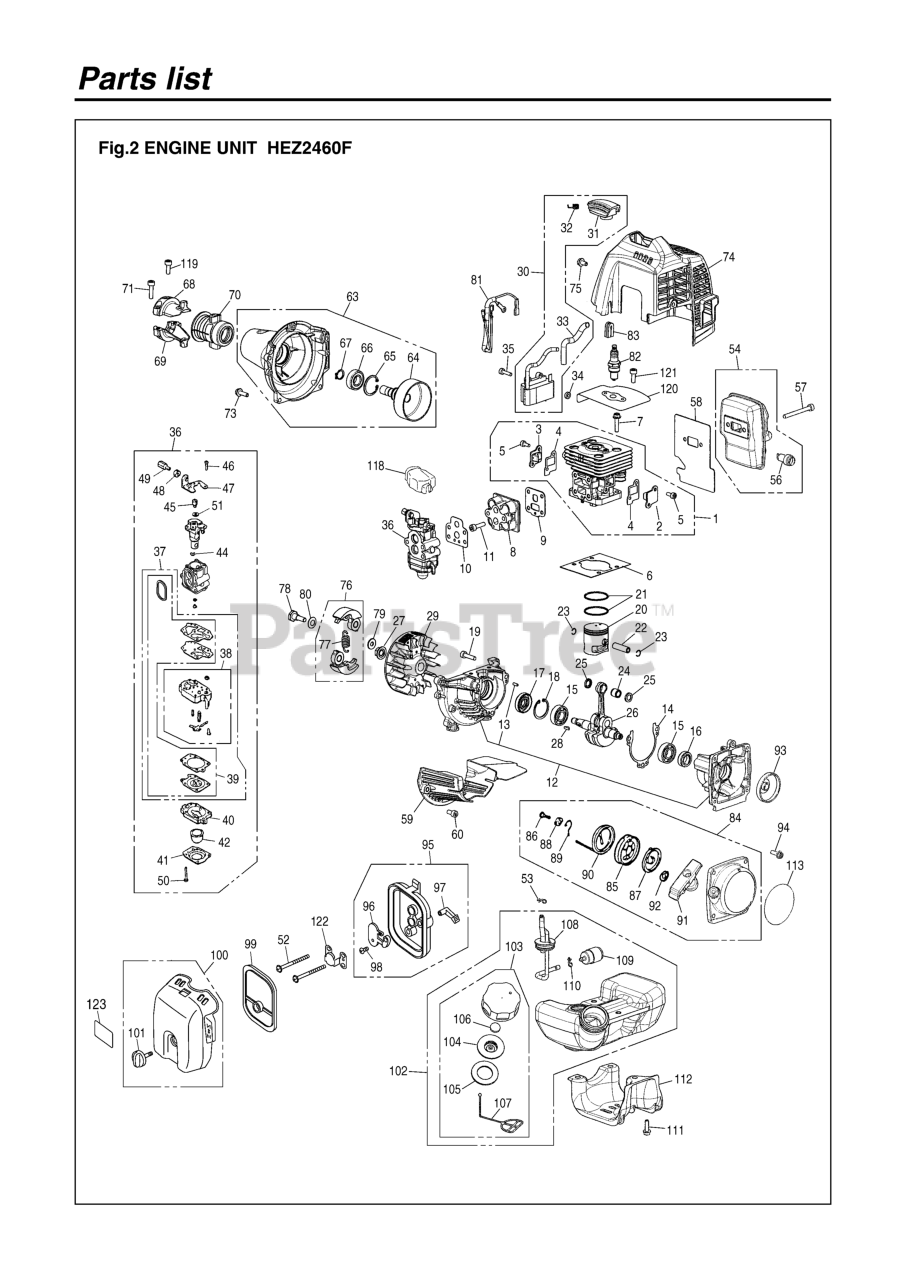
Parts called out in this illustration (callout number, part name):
1	CYLINDER COMP
2	COVER, TR-S
3	COVER, TR-F
4	GASKET, TR
5	BOLT
6	GASKET, BASE
7	BOLT
8	INSULATOR
9	INSULATOR GASKET
10	GASKET, CARB
11	BOLT, TORX
12	CRANKCASE-C
14	GASKET, CASE
15	BEARING MAIN
16	SEAL
17	SEAL, OIL (RPLS
19	BOLT (RPLS 28501
21	RING, PISTON
22	PIN, PISTON
23	RING, SNAP (RPLS
25	WASHER
26	CRANKSHAFT-C
27	NUT (RPLS 1140-4
28	KEY
30	COIL ASSY
31	CAP(RPLS 4810721
35	BOLT TORX
36	CARBURETOR ASSY
37	REBUILD KIT
38	BODY, PUMP
39	GASKET KIT
40	BODY, PURGE
41	COVER, PUMP
42	PUMP, PRIMING
49	SCREW
50	SCREW
51	WASHER
52	BOLT TORX
53	CLIP
56	ARRESTER
57	BOLT
58	GASKET, MUFFLER
60	BOLT
63	COVER, C
64	DRUM (RPLS 48103
68	BRACKET (A) (RPL
69	BRACKET (B)
70	CUSHION (RPLS T1
71	BOLT (RPLS 28501
73	BOLT
74	COVER, ENGINE
75	BOLT (RPLS T4950
76	SHOE COMP
77	SPRING
78	BOLT
79	WASHER
80	WASHER (RPLS 114
81	CORD COMP.
82	SPARKPLUG
83	GROMMET
84	RECOIL-A
85	REEL
86	SCREW
87	SPRING, SPIRAL
88	COLLAR
89	ARM
90	ROPE (RPLS 45007
91	KNOB (RPLS 3330-
92	PLATE, STOPPER
93	PULLEY
94	BOLT, TORX
95	CLEANER BODY ASS
96	PLATE, CHOKE
98	SCREW
99	ELEMENT
100	COVER ASSY
101	CLEANER KNOB
102	TANK ASSY
103	CAP ASSY
104	HOLDER (RPLS 450
105	PACKING
106	FILTER
107	STOPPER
108	PIPE-C
109	FILTER
110	CLIP (RPLS 28413
111	BOLT
112	GUARD, TANK
113	LABEL, RECOIL
118	COVER
119	BOLT
121	BOLT
